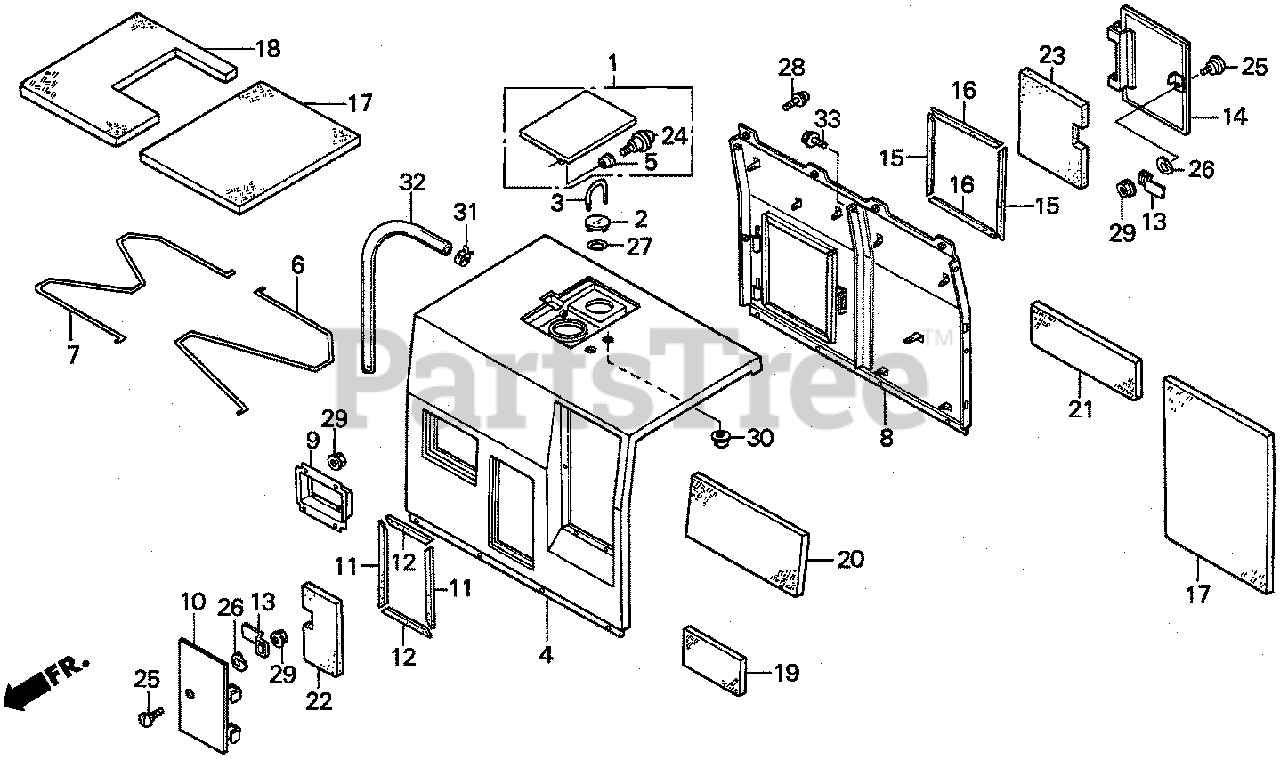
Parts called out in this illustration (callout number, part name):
1	COVER SET, FUEL CAP *R8* (BRIGHT RED)
2	CAP, FUEL METER
3	HOOK, HANGER
4	COVER, MAIN *R280* (POWER RED)
5	BUSH, FUEL CAP COVER
6	WIRE, R. INSULATOR HOLDER
7	WIRE, L. INSULATOR HOLDER
8	PANEL, RR. *R8* (BRIGHT RED)
9	CASE, REMOTE CONTROL PANEL
10	LID, FR. MAINTENANCE *R8* (BRIGHT RED)
11	SEAL A, MAINTENANCE LID
12	SEAL B, MAINTENANCE LID
13	PLATE, MAINTNENANCE LID LOCK
14	LID, RR. MAINTENANCE *R8* (BRIGHT RED)
15	SEAL, MAIN LID
16	SEAL, MAIN LID
17	INSULATOR A, MAINTENANCE LID COVER
18	INSULATOR B, MAINTENANCE LID COVER
19	INSULATOR C, MAINTENANCE LID COVER
20	INSULATOR E, MAINTENANCE LID COVER
21	INSULATOR, RR. PANEL (B)
22	INSULATOR, FR. MAINTENANCE LID
23	INSULATOR, RR. MAINTENANCE LID
24	SCREW, HEADLIGHT SETTING
25	BOLT, MAINTENANCE LID LOCK
26	WASHER, WAVE (12MM)
27	O-RING (56X2.4)
28	SCREW-WASHER (6X12)
29	NUT, FLANGE (6MM)
30	NUT, FLANGE (10MM)
31	CLIP, TUBE (A16)
32	BULK HOSE, VINYL (12X16X3000) (12X16X700)
33	BOLT, FLANGE (6X12)
